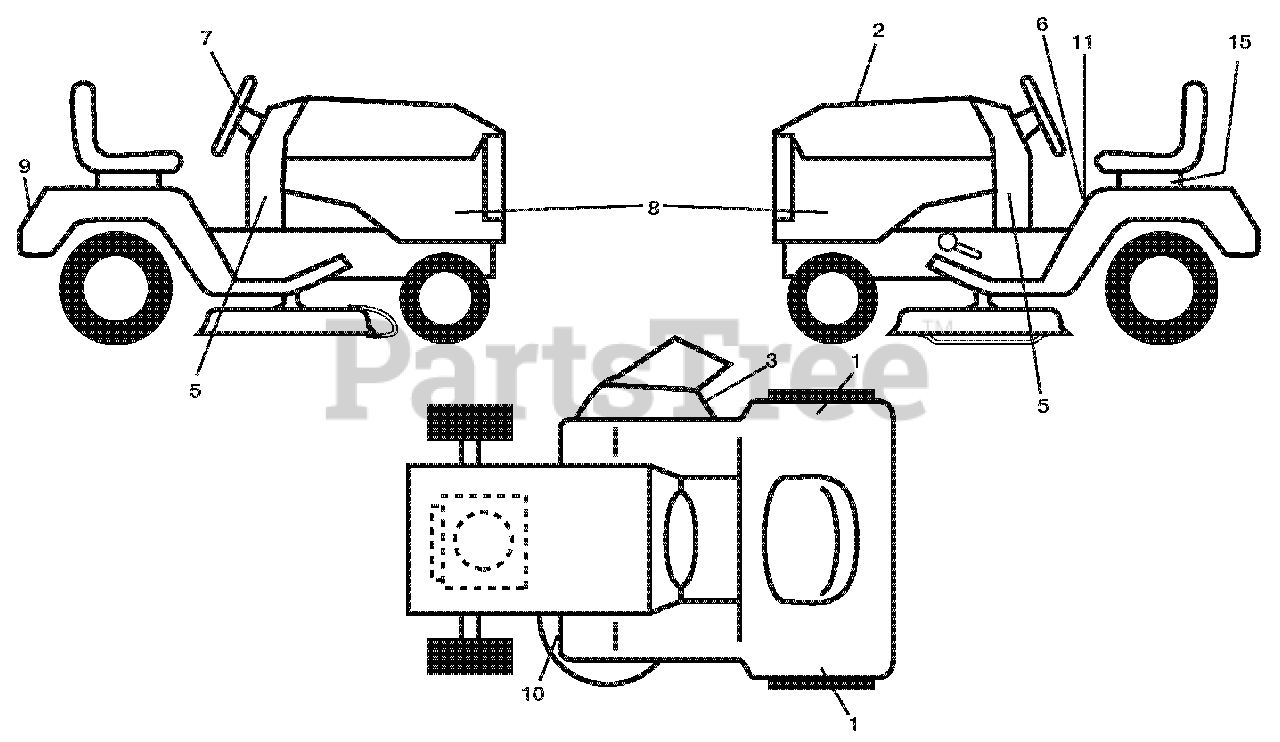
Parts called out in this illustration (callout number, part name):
1	DECAL.FENDER.SIDE.HYDRO
2	DECAL, REPLACEMENT
3	DECAL DECK/DEFLECT. WARNING
5	DECAL, DASH.LOWER
6	DECAL, FENDER.WARNING
7	DECAL.WHEEL.STEER.ARIENS
8	DECAL.SDPNL.PWRDBY KOHL.ARIENS
9	DECAL.FENDER.REAR.ARIENS
10	DECAL.V-BELT.SCH.
11	DECAL.FENDER
15	DECAL.BAT.DAN/POI P/L SYM.WPN
